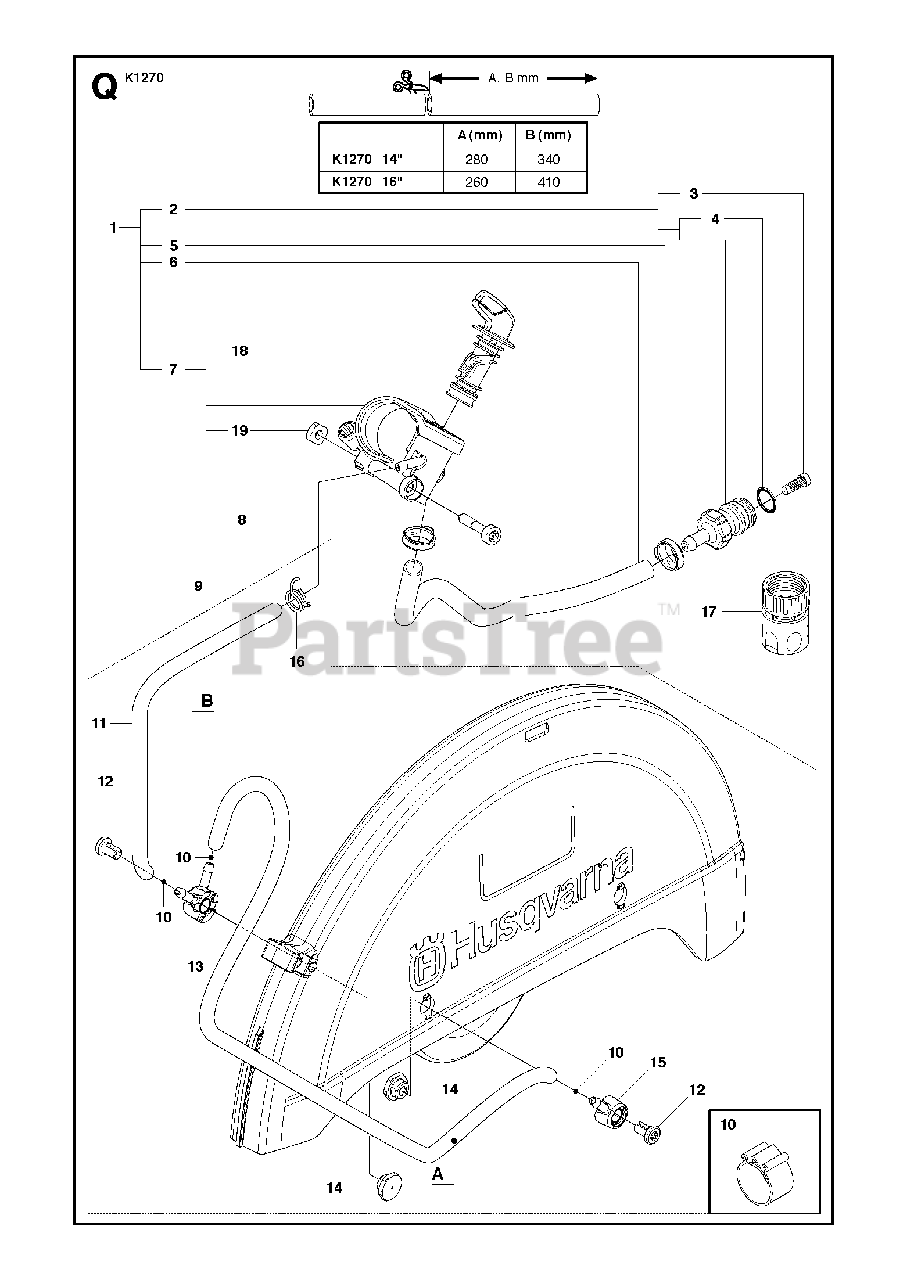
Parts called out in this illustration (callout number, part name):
8	SCREW ITXSCM
10	HOSE CLAMP
12	SCREW ITXSCM
17	COUPLER"1/2"""
17	COUPLER"GHT 3/4"""
18	LEVER ASSY
